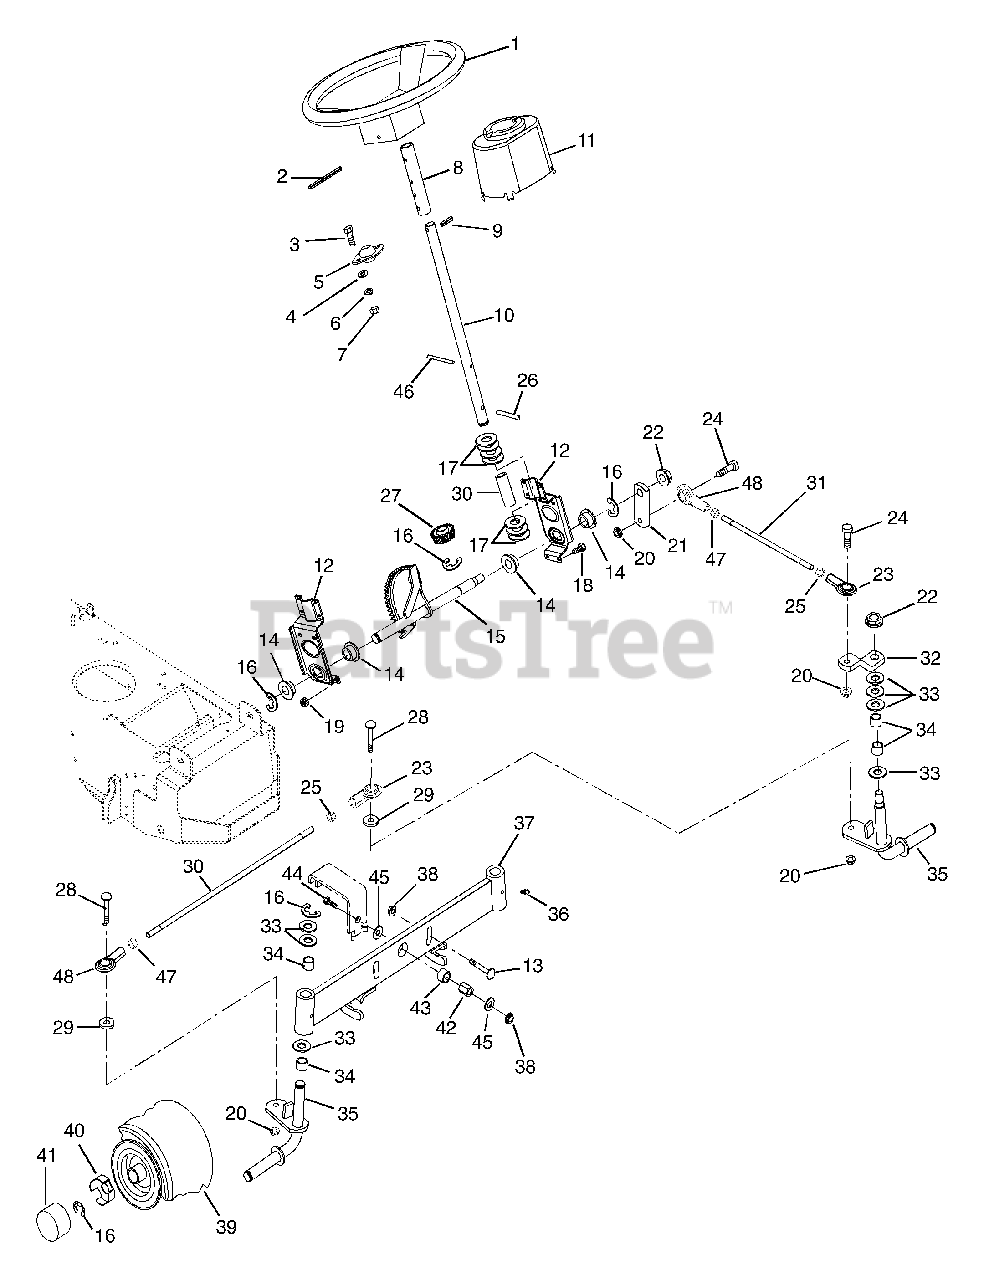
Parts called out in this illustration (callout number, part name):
1	STEERING WHEEL 13"
2	PIN-ROLL .250X1.75
3	@BLT-HEX .31-18X.75 GR5 YWZC
4	@WSHR-FL-STL.312X.734X.065 YWZ
5	BRG-FLG .751X2 HOLESX.81
6	WSHR-LK .312X.097 HVY YWZC
7	@NUT-HEX .31-18 YWZC
8	TUBE .754 X .999 X 5.00
9	PIN-ROLL .250X1.000
10	COLUMN, STEERING
11	CONE- STEERING COLUMN
12	BRACKET-STEERING GEAR
13	@BLT-HEX .38-16X1.50 GR5 YWZC
14	BSHG-FLG .750X1.093X.625X1.375
15	GEAR, STEERING
16	RG-RTNG-EXT .750X.050
17	WSHR-FL-STL.755X1.375X.062YWZC
18	@BLT-HEX .25-20X.75 GR5 YWZC
20	@NUT-LK-CTR .38-16 YWZC
21	ARM, STEERING ROD
22	NUT-LK .563-18 GR5 YWZC
23	ROD END, .38 RH
24	BLT-BTHD .38-16X1.25 GR5
25	NUT-JAM .375-24 YWZC
26	PIN .249X1.125 DRIV-LOK SP
27	PINION GEAR-STEERING
28	@BLT-HEX .38-16X1.75 GR5 YWZC
29	BSHG-SLV .377X.624X.370
30	ROD - TIE
30	BSHG-SLV .753 X 2.00 SELF LUB.
31	LINK - DRAG
32	ARM - STEERING SPINDLE
33	WSHR-FL-STL.755X1.375X.062YWZC
34	BSHG-SLV .750X.814X .750 BRZ
35	SPINDLE ASY, L.H
35	SPINDLE - LH
35	SPINDLE ASY., R.H
35	SPINDLE - RH
36	FTG-LUBE .25-28X.256 YWZC
37	AXLE, FRONT
38	@NUT-LK-CTR .38-16 YWZC
39	TIRE/WHEEL ASSY 15 X6.00-2 PLY
39	WHEEL W/BEARINGS
39	BSHG .75 BORE
39	FTG- LUBE .25-28X.97
39	BRG-BALL .752X1.380X.500
40	SPINDLE CUP
41	HUB CAP
42	BSHG-SLV .377X.623X.775 HEX
43	BSHG-SLV .626X1.000X.524 HEX
44	@BLT-HEX .38-16X1.75 GR5 YWZC
45	WSHR-FL-STL .380X1.50X.125YWZC
46	HOOD CATCH ASSY
47	NUT-JAM .375-24 LH YWZC
48	END, ROD-.38 LH
